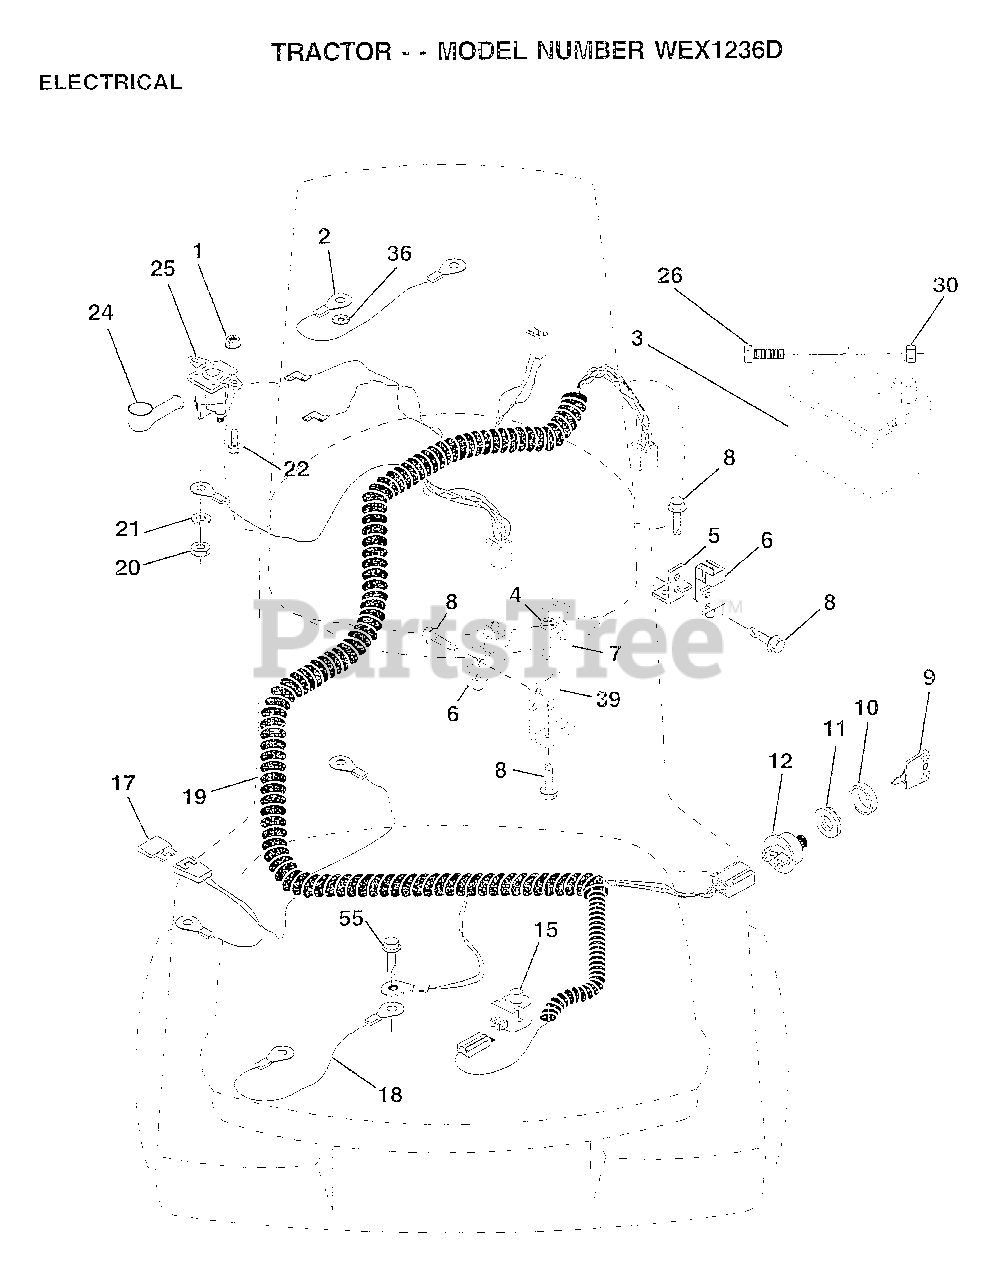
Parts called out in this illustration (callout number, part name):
1	NUT HXKEP 1/4X20
2	CABLE ASM.
4	LOCKNUT
5	BRACKET LT
6	SWITCH INTERLOCKT
7	KEEPER.ACTUAT.LR.
8	SCREW
9	KEY MLD GEN DELTA
10	COVER KEY SWITCH
12	SWITCH.IGNITION
15	SWITCH SEAT
17	FUSE.15 AMP
18	CABLE ASSY
19	HARNESS, IGNITION
20	NUT
22	BOLT HXHD FIN
26	BOLT LT
30	NUT
36	LOCKWASHER
39	BRACKET SWT CLUTC
55	SCREW LT
